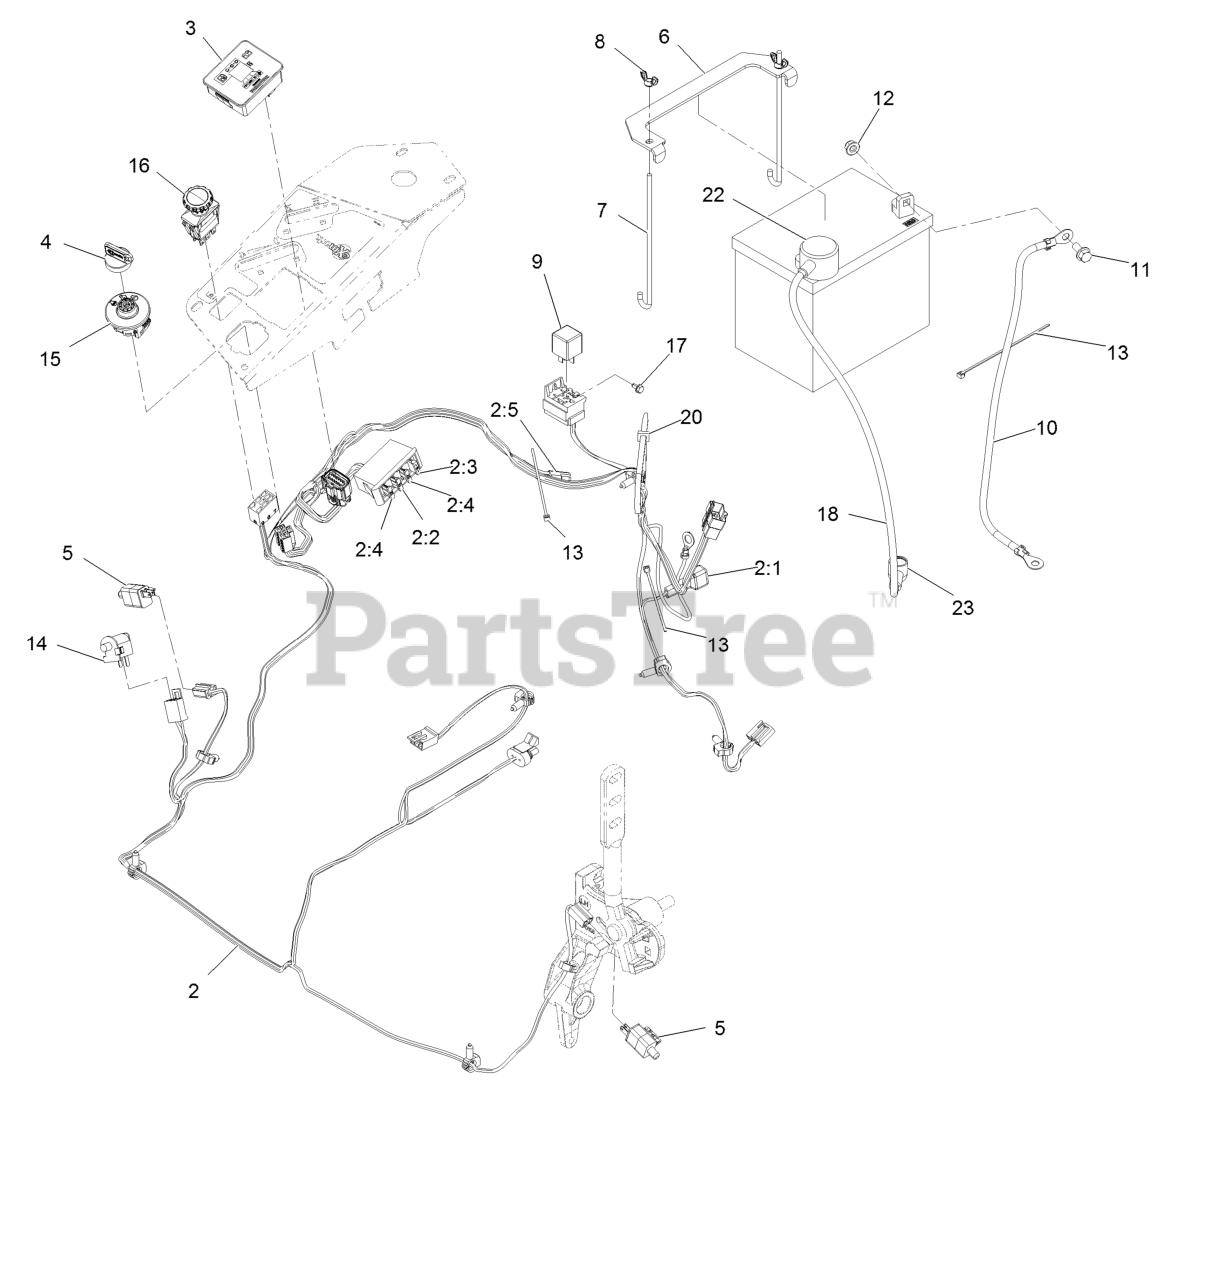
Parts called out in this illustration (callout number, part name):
2	Harness-Wire, Main
2:2	Fuse-Blade, 10 Amp
2:3	Fuse-Blade, 15 Amp
2:4	Fuse-Blade, 25 Amp
2:5	Cap-Plug
3	Fuel/Hour Meter ASM
4	Key-Ignition
4	Key-Exmark Logo
6	Strap-Tie Down, Battery
7	Bolt-Holddown
8	Wingnut-Nyloc 1/4-20
9	Relay-12Vdc 40 Amp
10	Cable-Battery, Negative
11	Screw-HH Flg 5/16-18 3/4
12	Nut-Nyloc 5/16-18 Flg
13	Tie-Cable 5 1/2 (Small)
15	Switch-Ignition
16	Switch-PTO, 10 Amp
17	Screw-HWH #10-24 x 2/8
18	Cable-Battery, Positive
20	Tie-Cable 7 15/16 (Large)
22	Insulator-Battery
23	Insulator-Solenoid
